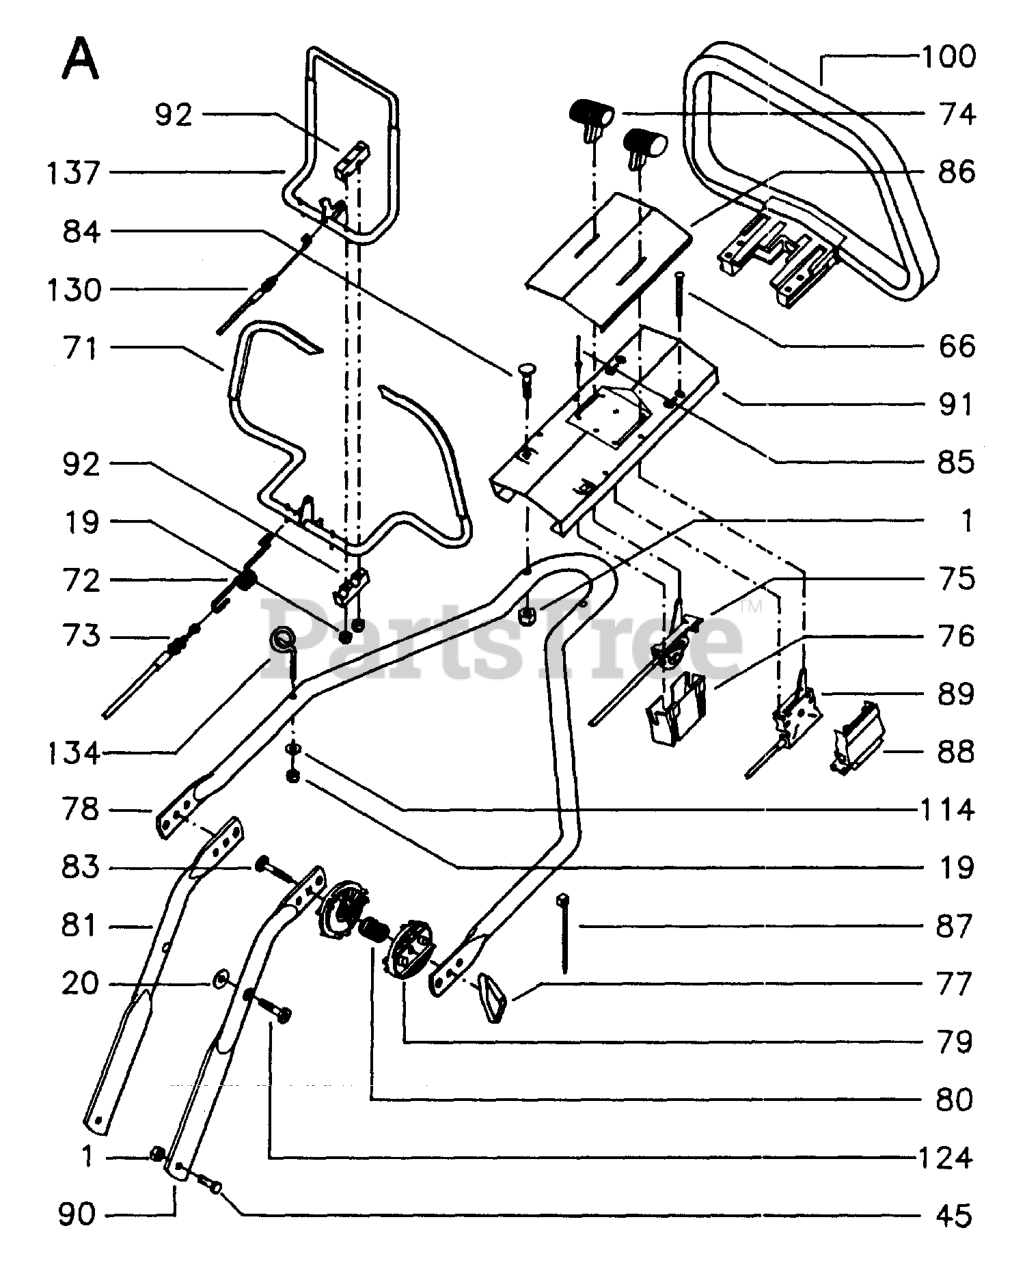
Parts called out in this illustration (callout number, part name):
1	LOCKNUT M8
19	LOCKNUT M6
45	SCREW M6S 8X25
74	KNOB
75	WIRE R 53S/SE
77	WINGNUT
90	HANDLE
134	CABLE GUIDE
